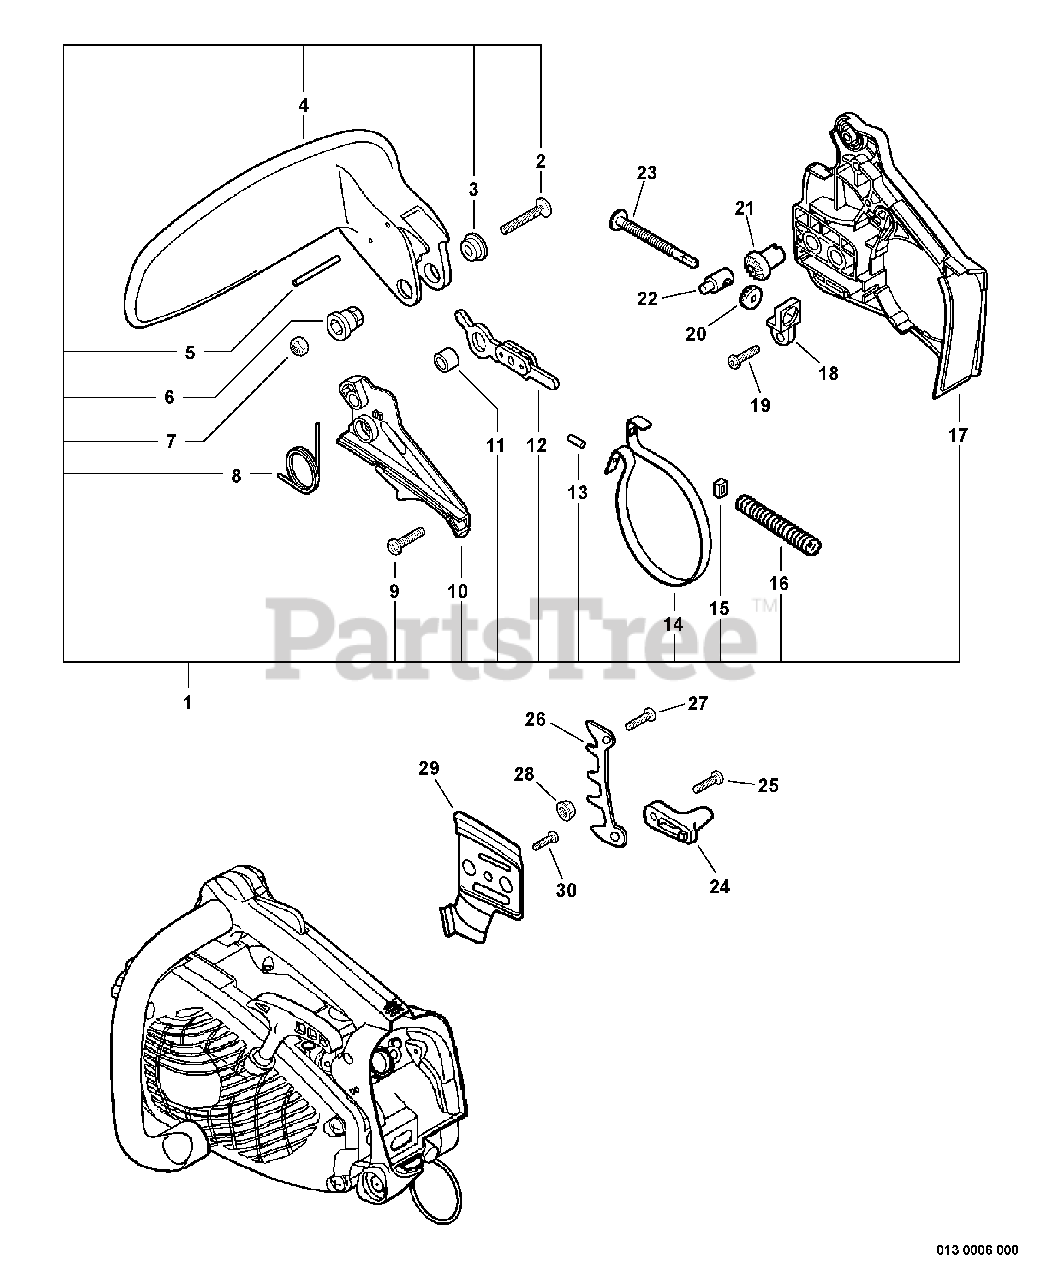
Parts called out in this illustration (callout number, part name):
1	CHAIN BRAKE ASSY
2	SCREW 5×32
3	COLLAR 5.3×10×13×L5
4	LEVER, BRAKE - ORANGE
5	PIN 3×26
6	COLLAR 5
7	NUT, LOCK M5
8	SPRING, TORSION
9	SCREW 4×12
10	COVER, BRAKE - GRAY
11	SPACER 8×12×9
12	CONNECTOR, BRAKE
13	PIN, SPRING 3x-9.8
14	BAND, BRAKE
16	SPRING, COMPRESSION
17	GUARD, SPROCKET - GRAY
18	COLLAR 8
19	SCREW 4×12
20	GEAR, BEVEL
21	GEAR, BEVEL
22	TENSIONER, CHAIN
24	CHAIN CATCHER
25	SCREW, TAPPING 5×20
26	SPIKE, BUMPER
27	SCREW, TAPPING 5×20
28	NUT, FLANGE M6
29	PLATE, GUIDE - INNER
30	SCREW 4×10
